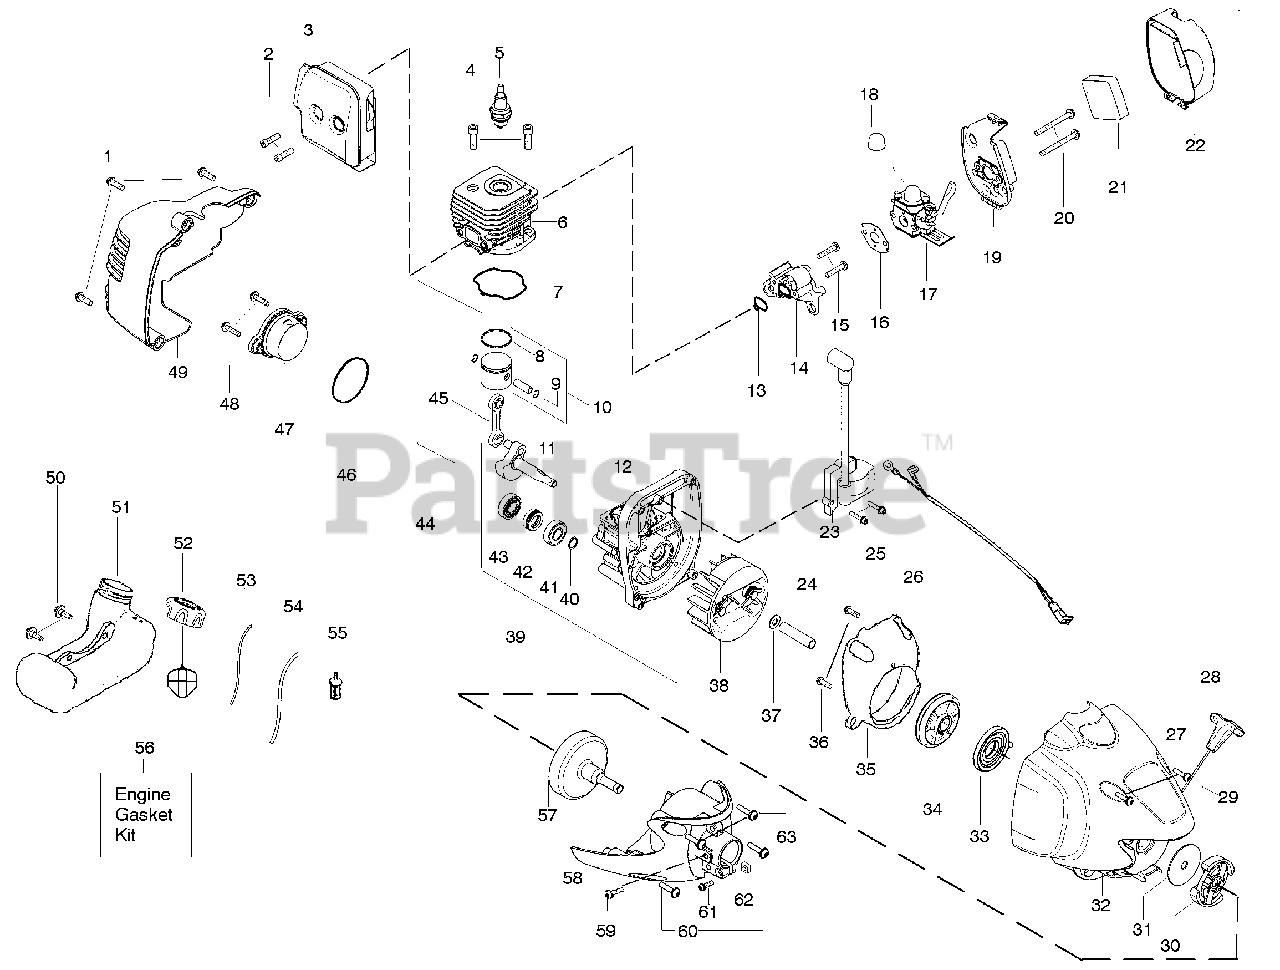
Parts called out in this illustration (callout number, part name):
2	Bolt-Muffler
3	Assy-Muffler/Shield
4	Screw-Cylinder
5	Spark Plug (RCJ 6Y)
6	Cylinder
7	Seal-Cylinder (kit)
8	Piston Ring
9	Retainer-Piston Pin
10	Kit - Piston
11	Assy-Crankshaft
12	Assy-Crankcase
13	Seal-Cyl/Carb.(kit)
14	Adapter-Carb.
16	Gasket-Carb. (kit)
17	Kit-Carb.(C1U-W19)
18	Bulb-Purge
21	Foam-Air Filter
22	Cover-Air Box
23	Ignition Module
24	Spacer-Flywheel
26	Assy-Switch wire
28	Handle-Starter
29	Kit - Rope
30	Assy-Clutch
31	Washer-Clutch
32	Assy.-Fan Hsg
33	Spring-Starter
34	Kit-Starter Pulley
37	Washer-Clutch Flat
38	Assy-Flywheel
39	Assy-C'case & C'shaft
40	Retain. Ring-C'shaft
41	Outer Bearing
42	Seal-C'shaft
43	Inner Bearing
44	Kit-piston/rod
45	Kit-Conn. Rod
46	O-Ring-C'case (kit)
47	Assy-Plug
49	Shroud-Rear
50	Retainer-Tank
51	Assy-Fuel Tank
52	Assy-Fuel Cap
53	Kit-Fuel Line (Small)
54	Kit-Fuel Line (Large)
55	Assy-Fuel Pickup
56	Kit-Engine Gasket
57	Assy-Clutch Drum
58	Assy-Clutch Cover
59	Screw-Align
61	Screw 12-24
62	Nut 12-24
